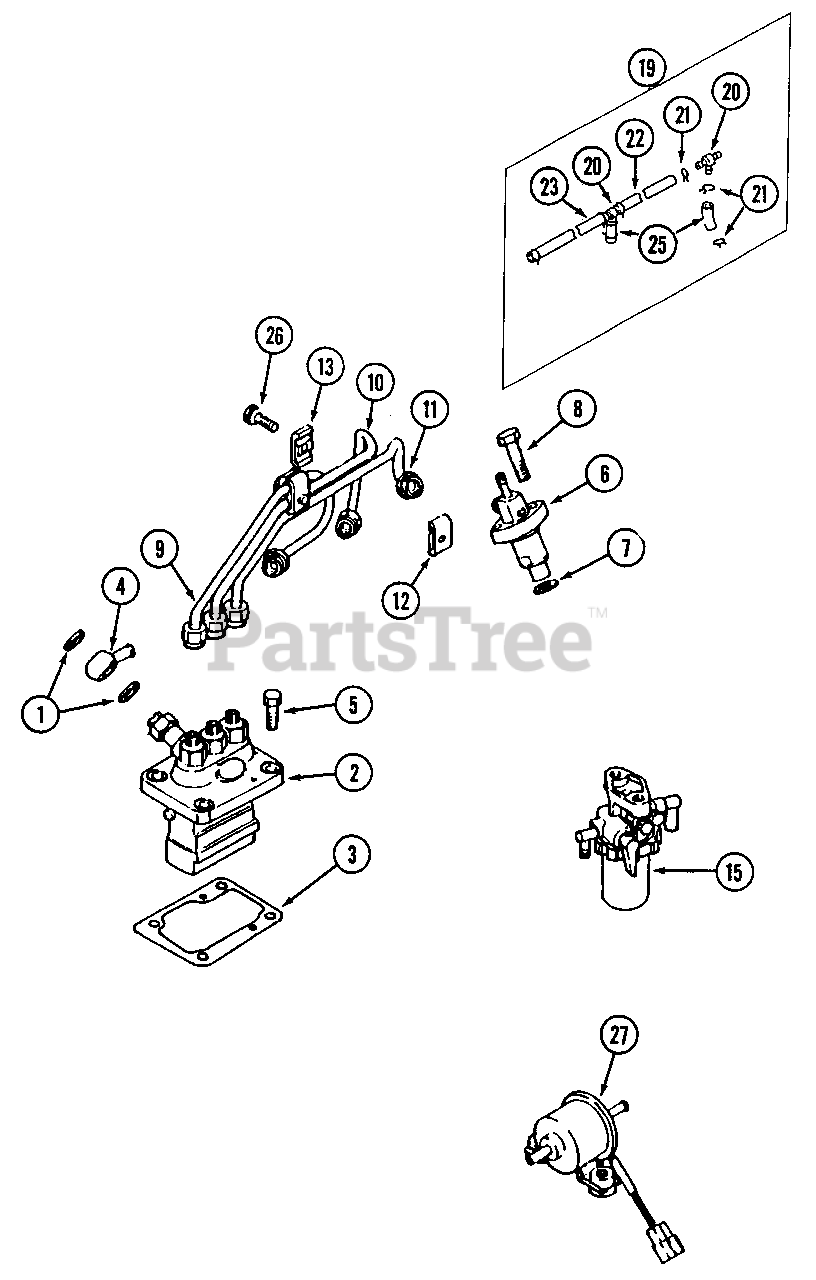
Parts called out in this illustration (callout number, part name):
2	Fuel Injection Pump Ass'y.
3	Shim Set, Adjusting
4	Collar, Union
5	Bolt
6	Nozzle & Nozzle Holder Ass'y.
7	Gasket, Nozzle Holder
9	Pipe Ass'y. No. 1 Fuel Injection
10	Pipe Ass'y. No. 2 Fuel Injection
11	Pipe Ass'y. No. 3 Fuel Injection
15	Fuel Filter Ass'y.
19	Pipe Ass'y., Fuel Return
21	Clamp, Hose
22	Pipe, Rubber
23	Pipe, Rubber
25	Pipe, Rubber
26	Bolt, w/Washer
27	Fuel Pump Ass'y.
